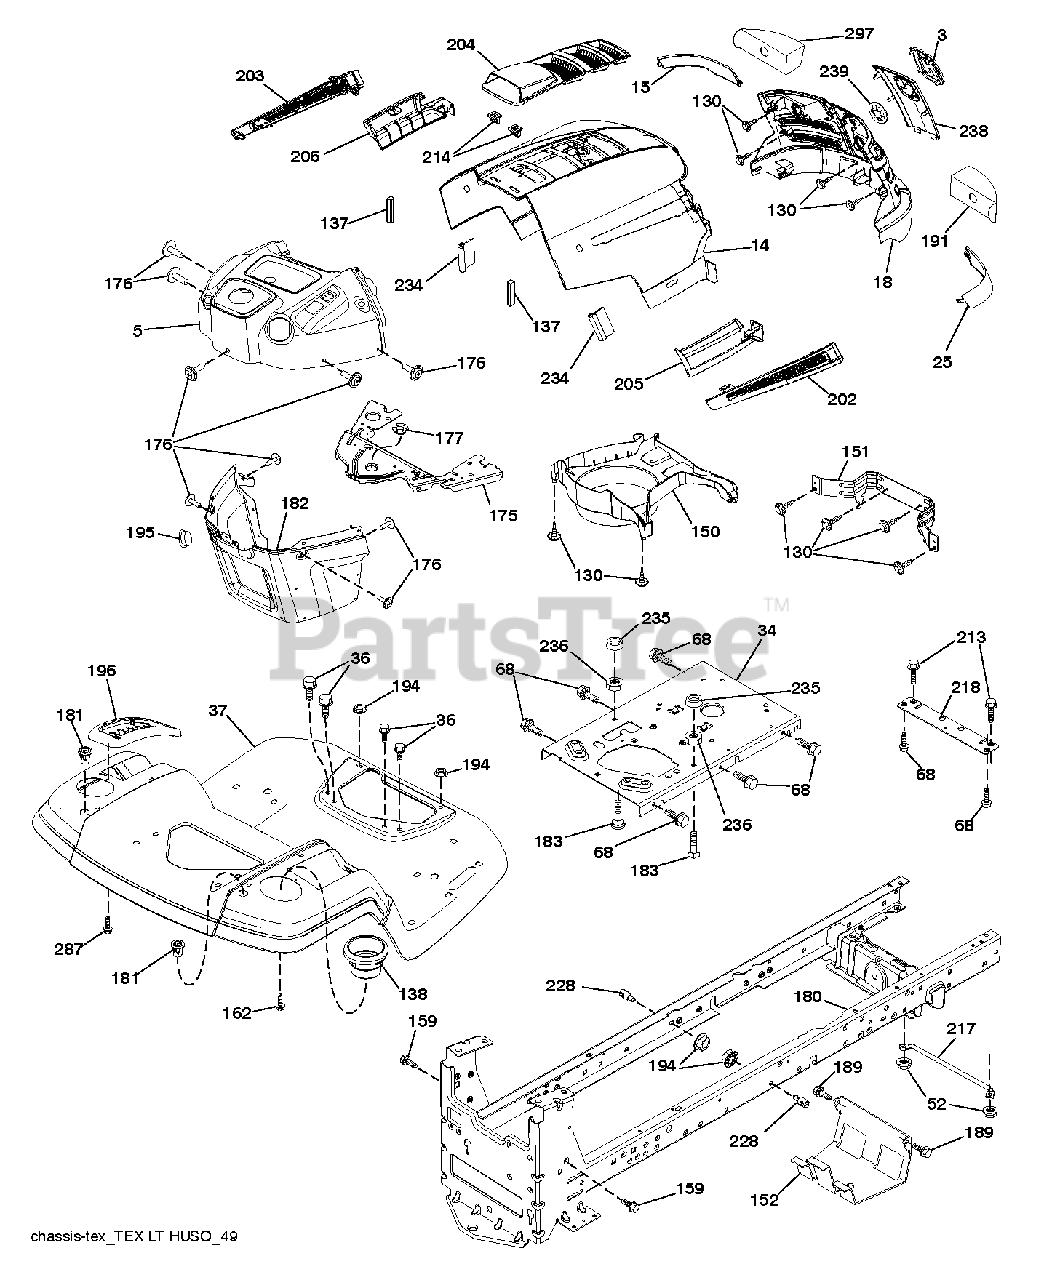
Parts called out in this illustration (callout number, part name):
3	LOGO.HUSQ.GT.LT.CROWN.H
5	SUBASM.DASH.UPPER.W/BUMPER
14	HOOD.HUSQVARNA.LT.ORANGE
15	LENS.HUSQVARNA LT.RH
18	GRILLE.SVC.HUSQVARNA.GREY
25	LENS.HUSQVARNA LT.RH
34	PLATE.ENGINE.WELDED.CHASSIS
36	SCREW 5/16"
37	FENDER.TLT.FS.W/CUPHLD.ORANGE
52	LOCKNUT
68	SCREW LT
130	SCREW.#10 X 0.750.BOS
137	BUMPER DASH
138	HOLDER.CUP.LT.GREY
151	BRACKET PIVOT
152	SHIELD.BROWNING.W/TEX
159	SCREW, 3/8-16X3/4
162	SCREW.HI-LO.CONSOLE
175	CROSSMEMBER
176	SCREW.#10-24X5/8.RN.QU
177	BUSHING STEERING
180	CHASSIS
181	BUSHING.MNT.FEND.CRGO.TEX.49
182	DASH.LOWER.PREDATOR LT
183	BOLT.5/16-18X1-1/4 FULL THD
189	SCREW
191	INSERT.REFLECTIVE.RH.
194	NUT LOCK HEX FLANGE 5/16-18
195	PLUG.TEX.DASH.SVC.MINDER.GREY
196	DECKLFT.CONSOL FULL ASSM GREY
202	VENT.SIDE.HUSQVARNA.LT.RT
203	VENT.SIDE.HUSQVARNA.LT.LFT
204	SUBASM.TOP.VENT.HUSQ.LT
205	SKIRT.SIDE.HUSQVARNA.LT.RT
206	SKIRT.SIDE.HUSQVARNA.LT.LEFT
213	BOLT
214	CLIP.RETAINER.TINNER.
217	ROD.PIVOT.HOOD
218	X-PIECE.HOOD.STOP.NON/
228	STUD.FASTNER.W/ANTI-ROTATE
234	BUMPER.HOOD.TEX.HUSQVARNA
235	SPACER FENDER
236	NUT.CENTERLOCK.5/16-
238	TRIM.HUSQ LT.668
287	SCREW 1/4X20
297	INSERT REFLECTIVE
